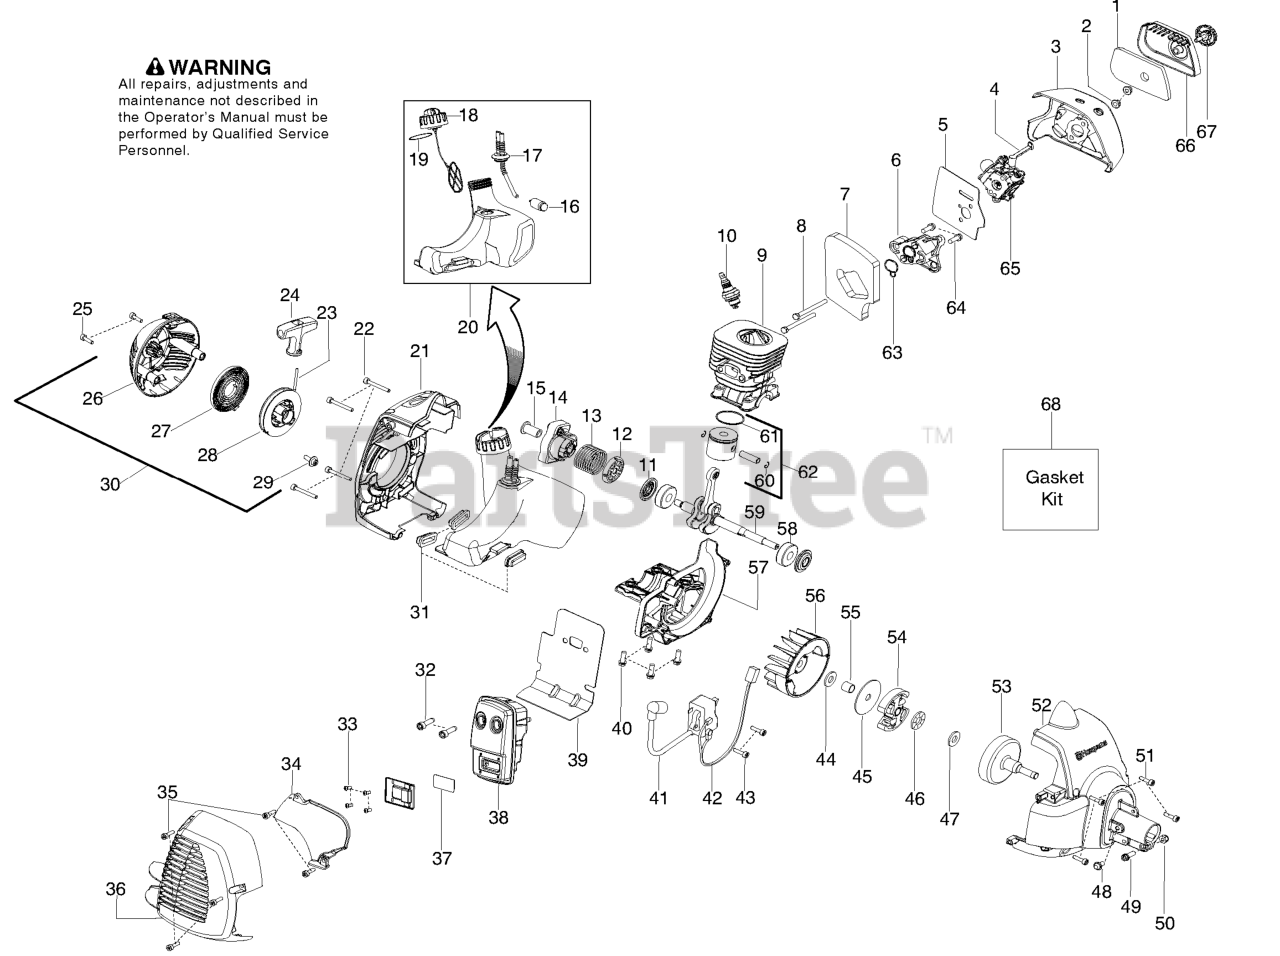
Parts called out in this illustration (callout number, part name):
1	FILTER AIRBOX
3	RP_AIR BOX
4	CHOKE LEVER
5	KIT GASKET CARB
6	CARB ADAPTOR
7	KIT GASKET 28CC
8	BOLT CARB ADAPTOR
9	CYLINDER
10	Plug-Spark (RCJ-8Y)
11	KIT SEAL CRANKSHAFT
12	WASHER STARTER
13	SPRING STARTER CUP
14	ASSY STARTER CUP
15	COUPLING STARTER
16	FUEL PICK-UP ASSY
17	KIT FUEL LINE
18	ASSY-CAP W/RETAINER
19	KIT GASKET 28CC
20	FUEL TANK ASSY
21	REAR SHROUD
24	STARTER HANDLE GRAY
25	SCREW M5-0.8X30MM
26	STARTER HOUSING
27	%KIT STARTER SPRING
28	KIT STARTER PULLEY
30	ASSY-STARTER HSG.
31	ISOLATOR FUEL TANK
32	BOLT MUFFLER
33	SCREW-10-16 X 1/2 HI-LO
34	SHIELD HEAT
35	SCREW M4 X 1.75 PT 16MM
36	GUARD-MUFFLER
37	KIT SPARK ARRESTOR SCREEN
38	ASSY-MUFFLER
39	KIT GASKET 28CC
40	SCREW-M5-0.8 X 25MM(TAP)
41	IGNITION MODULE MBU-7
42	ASSY MODULE LEAD WIRE
43	SCREW M4 X .70 TT 16MM
44	WASHER CLUTCH
45	WASHER-CLUTCH
46	BEARING THRUST
47	WASHER THRUST
50	LOCKNUT-HEX 10-24
51	SCREW M4 X .70 TT 16MM
52	FAN HSG ASSY
53	ASSY-CLUTCH DRUM
54	%KIT CLUTCH ASSY
55	SPACER FLYWHEEL
57	CRANKCASE CASTING
58	BEARING RADIAL BALL (6201)
59	KIT CRANKSHAFT ASSY
60	WRIST PIN RET.
61	RING PISTON
62	KIT PISTON 28CC TRIMMER
63	KIT GASKET 28CC
64	SCREW-M5-0.8 X 25MM(TAP)
65	Kit-Carb.
66	COVER-AIR BOX
67	KNOB ASSY AIRBOX COVER
68	KIT GASKET 28CC
